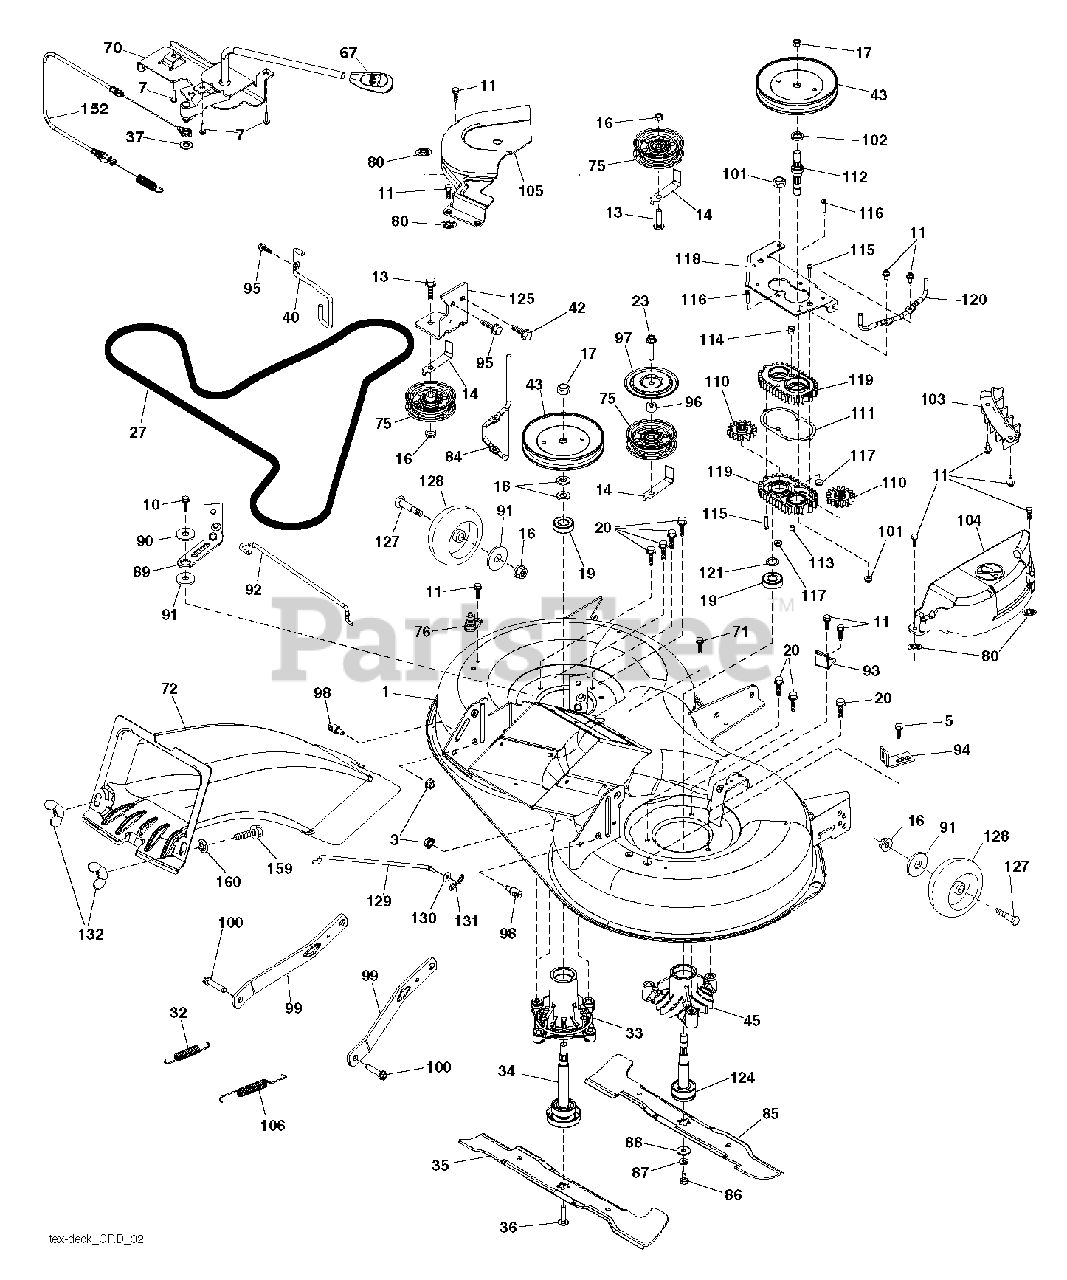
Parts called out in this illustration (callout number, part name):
3	NUT LOCK HEX FLANGE 5/16-18
5	BOLT.5/16HEX.WHS.HD
7	SCREW.#10 X 0.750.BOS THREAD
10	SCREW 3/8-16X1
11	SCREW.1/4-20X5/8
13	BOLT.3/8-16X1.50
14	KEEPER, BELT IDLER
16	NUT LOCK FLG 3/8-16 UNC
17	NUT.FLANGE.LOCK.TOP
18	WASHER.SPACER.MANDREL
20	SCREW, WASHER HEAD
23	SCREW LT
32	SPRING RETURN
33	HOUSING MANDREL
34	SHAFT.ASM.MDRL.N/GREASE.38
35	BLADE.3N1.LH.CRD.97
36	BOLT.WASHER.ASM.7/16-2
40	KEEPER BELT ENGINE LH
42	SCREW
43	PULLEY.MANDREL.5.438.PD
45	HOUSING.MANDREL
67	HANDLE.CLUTCH.CABLE.LT
70	CLUTCH.ASM.MANUAL.LT.PRED
71	SCREW 3/8-16X1/2
75	FLAT IDLER PULLEY
76	PORT.WASHOUT
80	PALNUT 1/4
84	KEEPER.BELT.MANDREL.PULLEY
85	BLADE.3N1.RH.CRD.97
87	LOCKWASHER
88	WASHER.BLADE
90	SPACER.RETAINER
94	BRKT.CLUTCH.CABLE
95	SCREW, 3/8-16X3/4
98	STUD.FASTNER.W/ANTI-ROTATE
99	ARM.SUSPENSION.MOWER.R
100	BOLT.SHOULDER
102	SPACER BEARING
106	SPRING.BRAKE.RETURN.38"
117	NUT T
127	BOLT.SHOULDER.3/8-16X3-5/8
128	WHEEL. GUAGE RALLY
129	ROD.ANTI.SWAY.48/54"K4
130	WASHER
131	PIN.COTTER.5/16.BOW TI
132	KNOB.HANDLE.3/8.TRI-POINT.BLAC
159	BOLT
